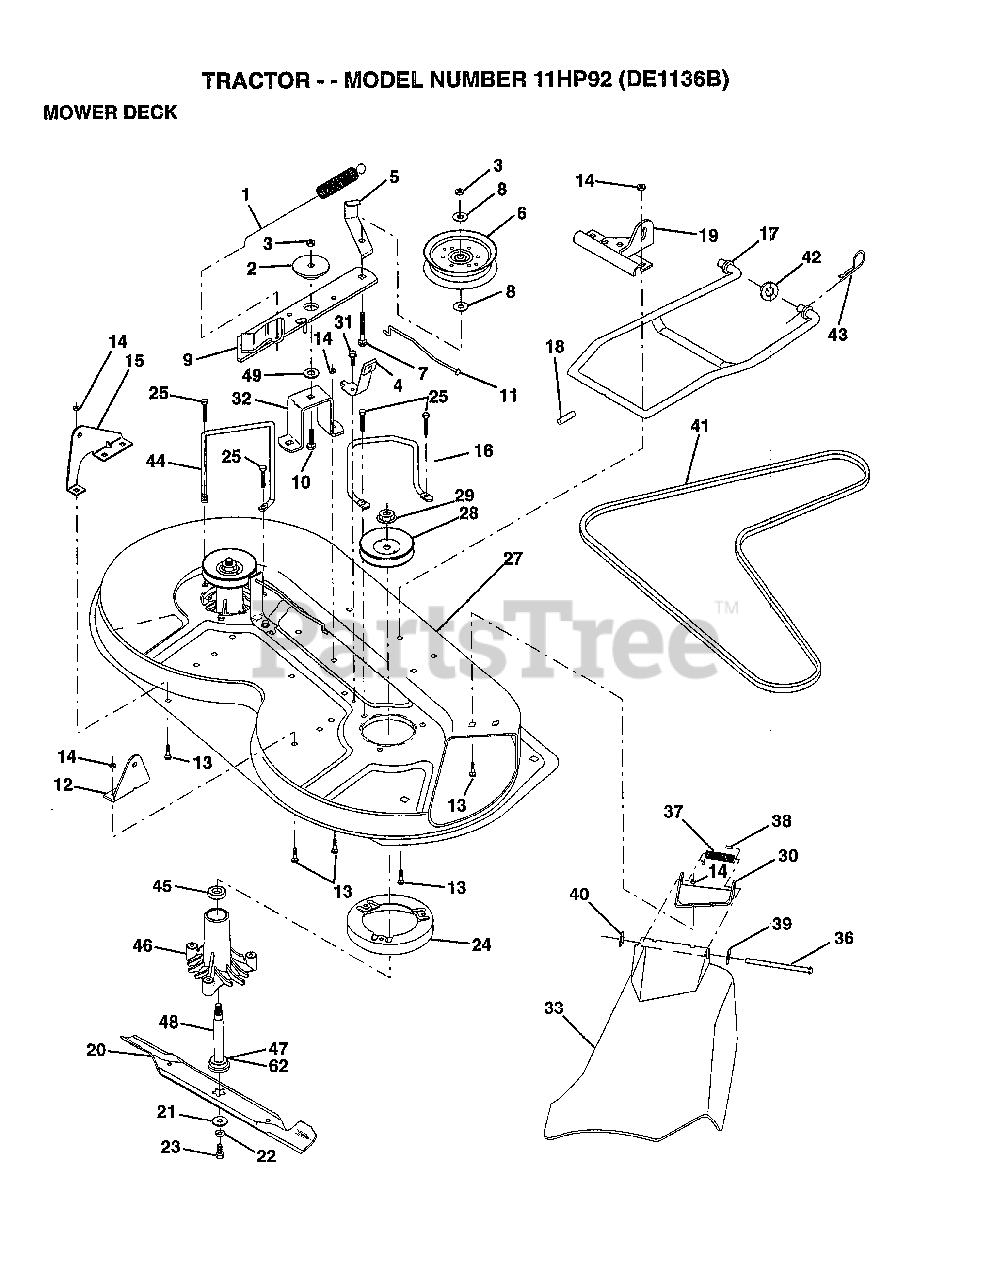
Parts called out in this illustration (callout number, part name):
1	SPRING CLUTCH MWR
2	SPACER RETAINER
4	BRAKE ASM
5	IDLER BELT GUIDE
6	PULLEY IDLER
7	BOLT
8	WASHER
10	BOLT.3/8-14X1.25
11	BRAKE ROD
12	"BRKT,LIFT REAR"
13	BOLT
15	"BRKT,LIFT REAR LH"
16	"KEEPER-BELT,RH"
17	MOWER LINK STAB
18	"PIN,GROOVE"
19	"BRKT,LINK STABILI"
20	"BLADE.36"" HIPERF"
21	WASHER.HARD.BLADE
23	BLADE BOLT
24	STRIPPER RND MWR
25	"SCREW-THD ROLL,WA"
27	"HOUSING-MOWER,36"""
28	PULLEY.MAND.36/46
31	SCREW LT
32	"SUPT,IDLER ARM"
36	HINGE ROD
37	SPRING TORSION
38	CAP-SLEEVE LT
39	WASHER
40	NUT PUSH M
41	V-BELT.PRIM.78.5.
43	RETAINER.SPRING
44	KEEPER BELT LH
45	BEARING
46	HSG ASM MANDREL
47	BEARING.BALL
49	HARDENED WASHER
62	WASHER.FELT.
